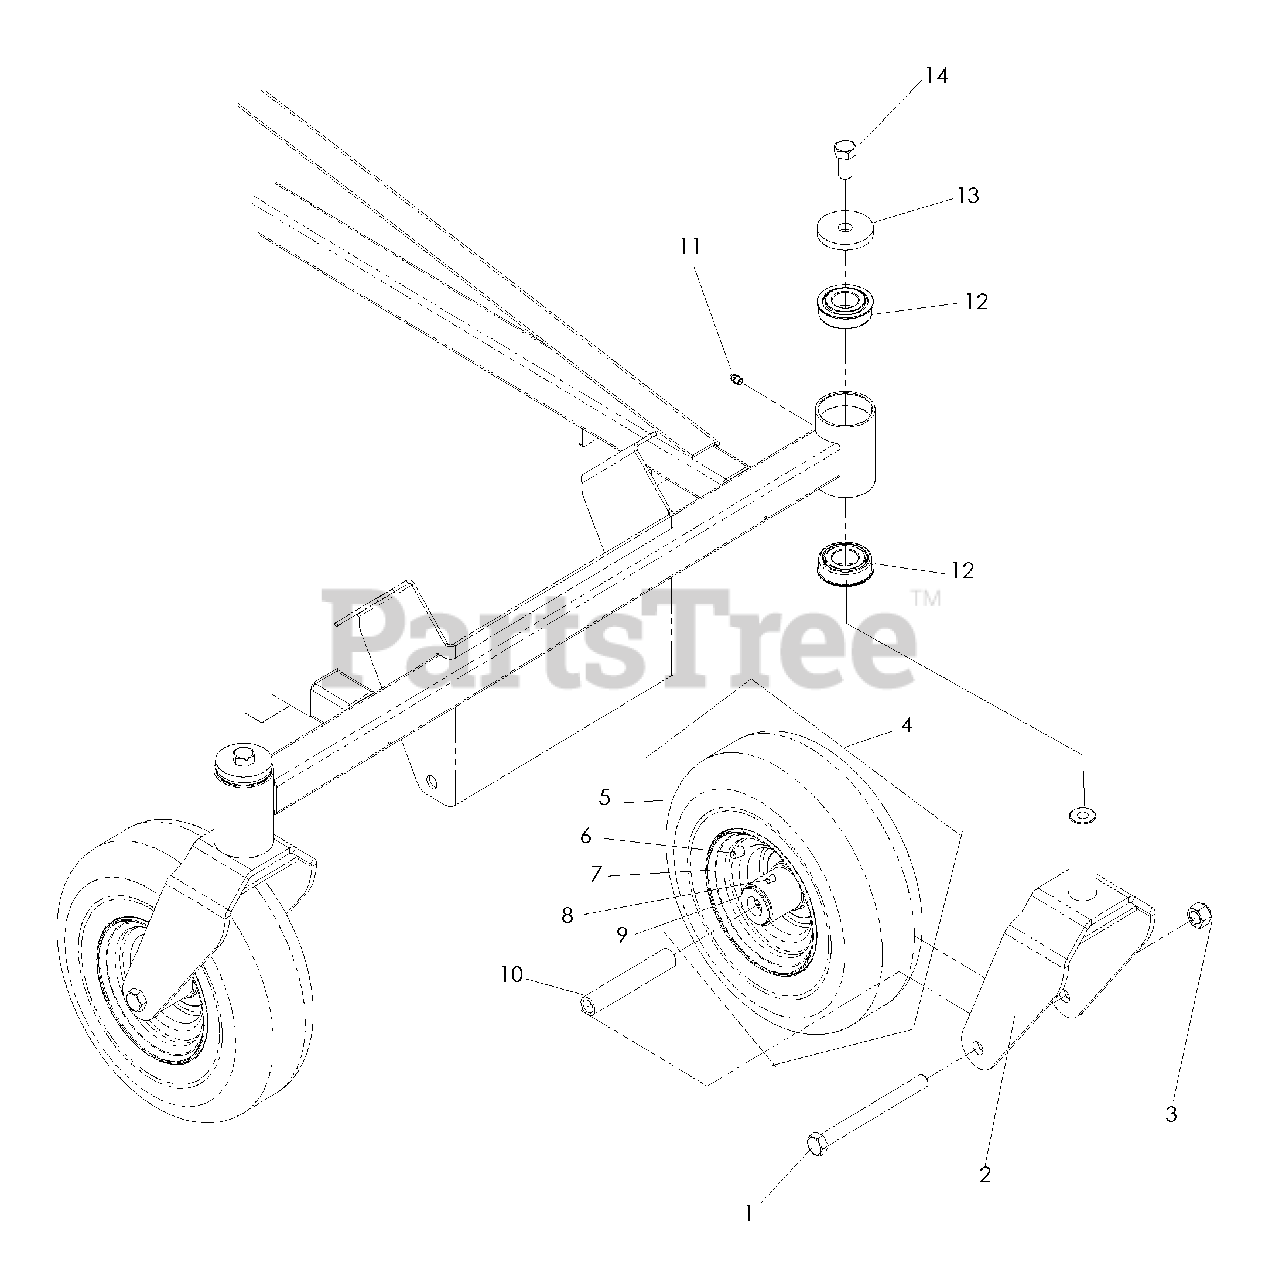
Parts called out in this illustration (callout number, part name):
1	HCS 1/2-13 x 5 1/2
2	CASTER YOKE
3	NUT 1/2-13 NYLOC
4	CASTER TIRE, COMPLETE
5	TIRE, 4 PLY, 410/350-5
6	VALVE STEM
8	ZERK
9	BEARING, FLANGED
12	BEARING, FLANGED
13	HEAVY WASHER
14	HCS 1/2-13 x 1
